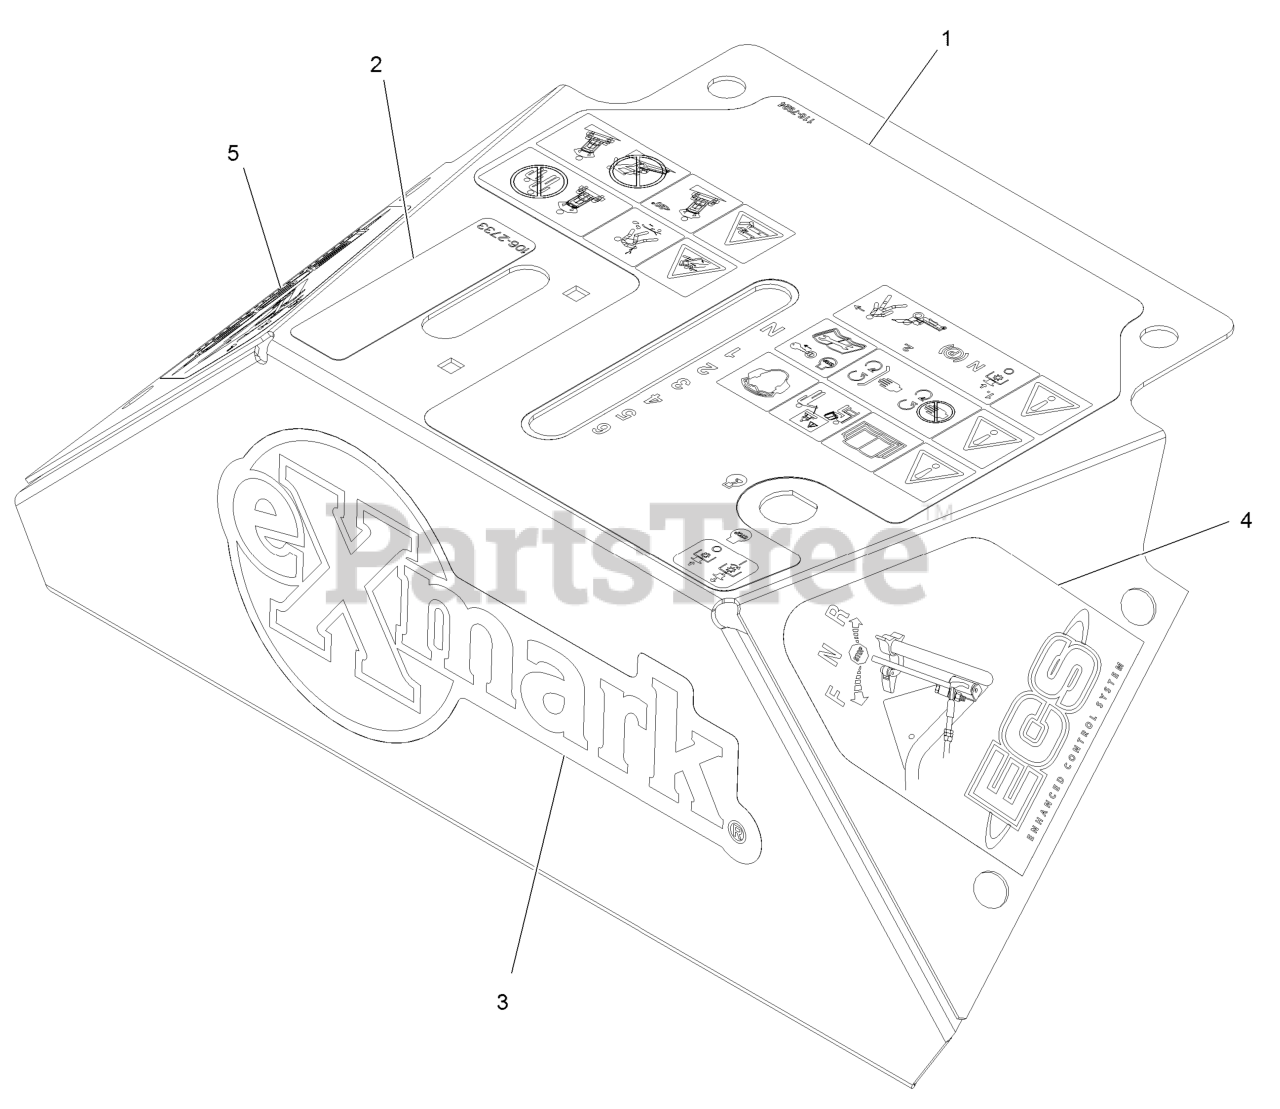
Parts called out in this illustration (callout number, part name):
1	Decal-Console Vh Ecs
2	DECAL-THROTTLE
3	DECAL,EXMARK LOGO
4	DECAL,LH ECS INSTRUCTION
5	DECAL,RH ECS INSTRUCTION
